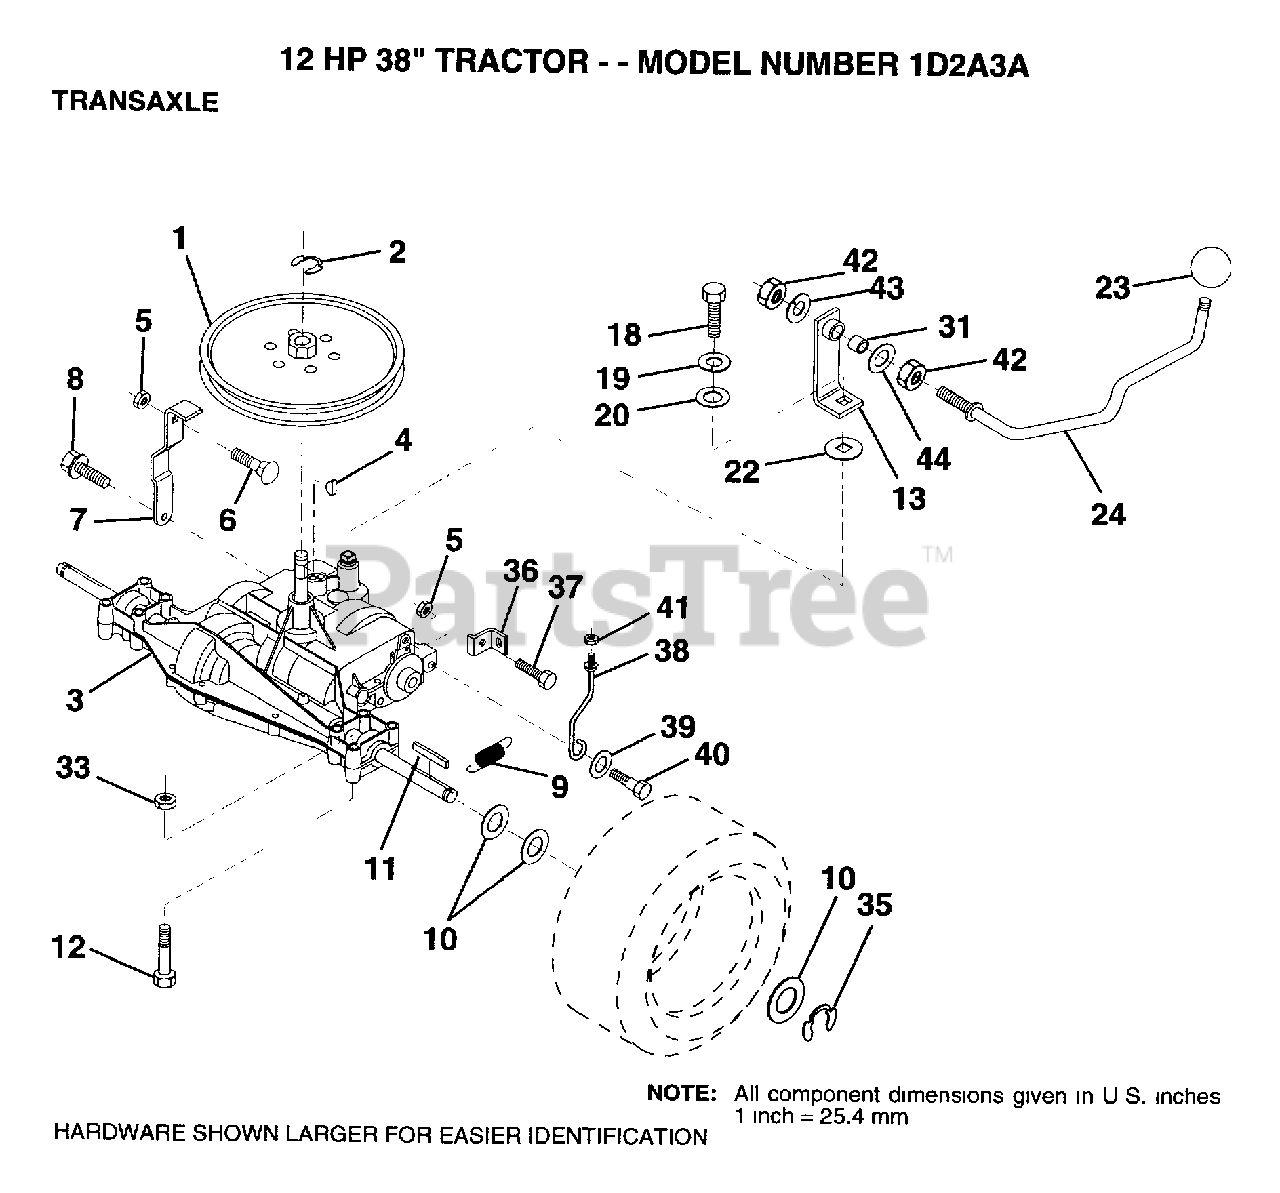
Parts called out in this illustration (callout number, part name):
1	PULLEY
3	TRANSAXLE DANA 6 SP
6	BOLT
7	STRAP.TORQUE.LH
8	SCREW
10	WASHER
11	SQUARE KEY
12	BOLT
13	BRACKET.ASM.SHIFT
19	LOCKWASHER
20	WASHER LT
22	WASH-SHFT PLT LT
23	KNOB T (1/2-HOLE)
24	ROD.SHIFT.CNTR.LR
35	E-RING LT
36	BRACKET.BRAKE
37	BOLT
38	KEEPER.BELT.RH
40	BOLT SHD 5/16-18
41	NUT
42	NUT
43	LOCKWASHER
44	WASHER
